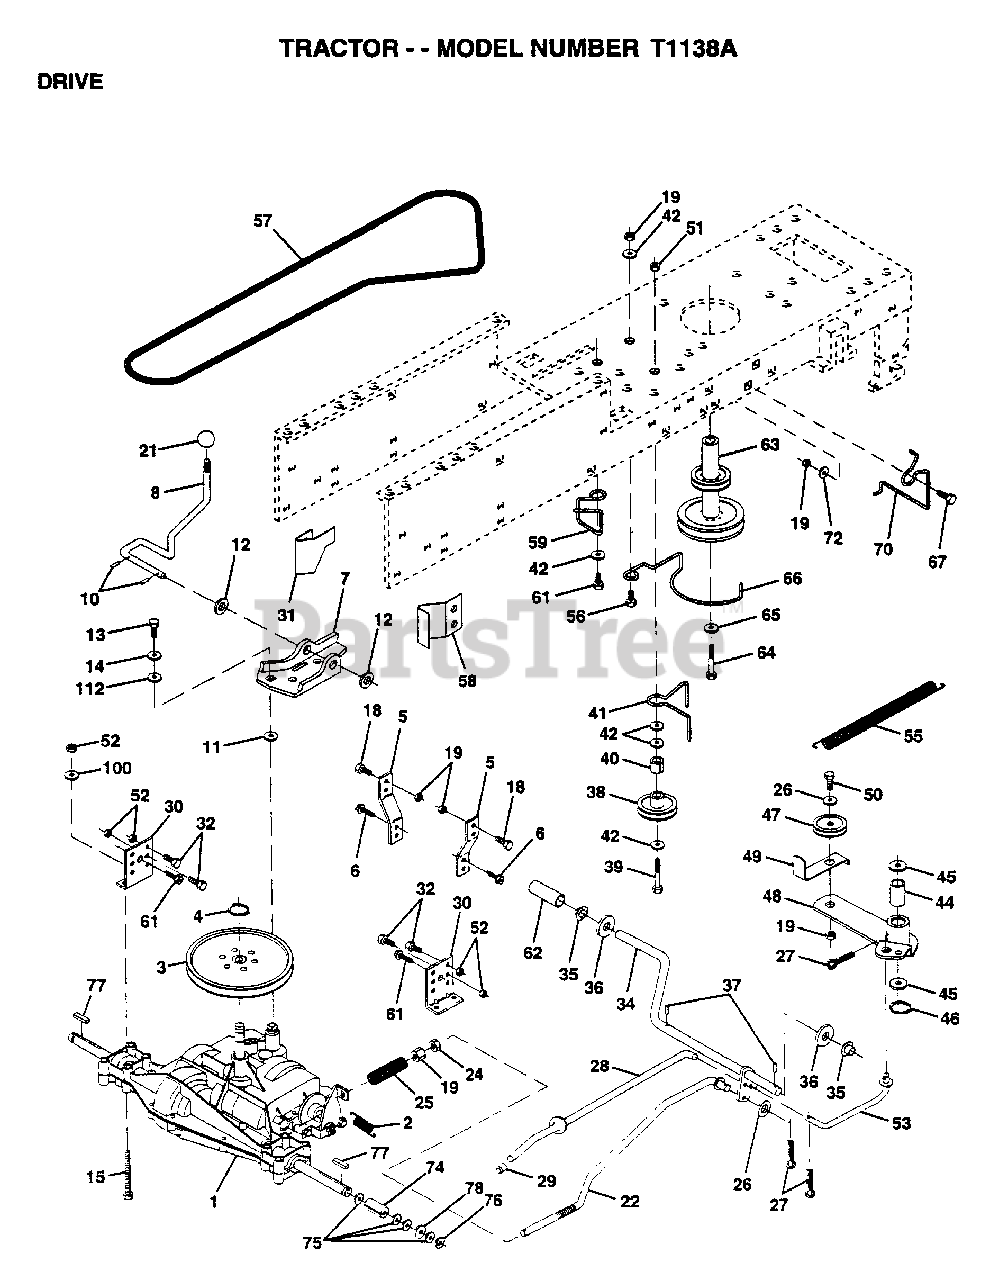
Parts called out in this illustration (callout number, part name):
2	SPRING.BRAKE.RETU
3	PULLEY TRANS
5	STRAP TORQUE
6	SCREW
8	SHIFT ROD
10	PIN COTTER 1/8
11	WASH-SHFT PLT LT
12	WASHER
13	BOLT.1/4-28.W/PAT
14	LOCKWASHER
15	BOLT HEX
18	BOLT
19	NUT
21	CONTROL KNOB LT
22	BRAKE ROD
24	NUT
25	SPRING ROD LT
26	WASHER
27	COTTER PIN
28	ROD.BRAKE.PARK.LT
30	TRANSAXLE MTG BKT
31	"KEEPER,BELT LH T"
32	BOLT
34	SHAFT.PEDAL.FOOT
35	NYLON BEARING
36	WASHER LT
38	PULLEY.IDLER.FLAT
39	BOLT
40	SPACER T
41	BELT KEEPER LT
42	WASHER
44	"LY, BEARING"
45	WASHER LT
46	KLIP RING
48	ARM IDLER
49	RETAIN BELT
53	"LINK, CLUTCH T"
55	"SPRING, RETURN LT"
58	"KEEPER,BELT RH T"
59	KEEPER BELT CNTSP
61	SCREW
62	PEDAL COVER T
63	PULLEY.ENGINE
64	BOLT
65	LOCKWASHER
66	KEEPER.BELT.ENG.L
67	BOLT
70	KEEPER BELT ENG
72	WASHER
74	SPACER LT
75	WASHER
76	E-RING LT
77	SQUARE KEY
78	WASHER
100	WASHER M
112	WASHER LT
